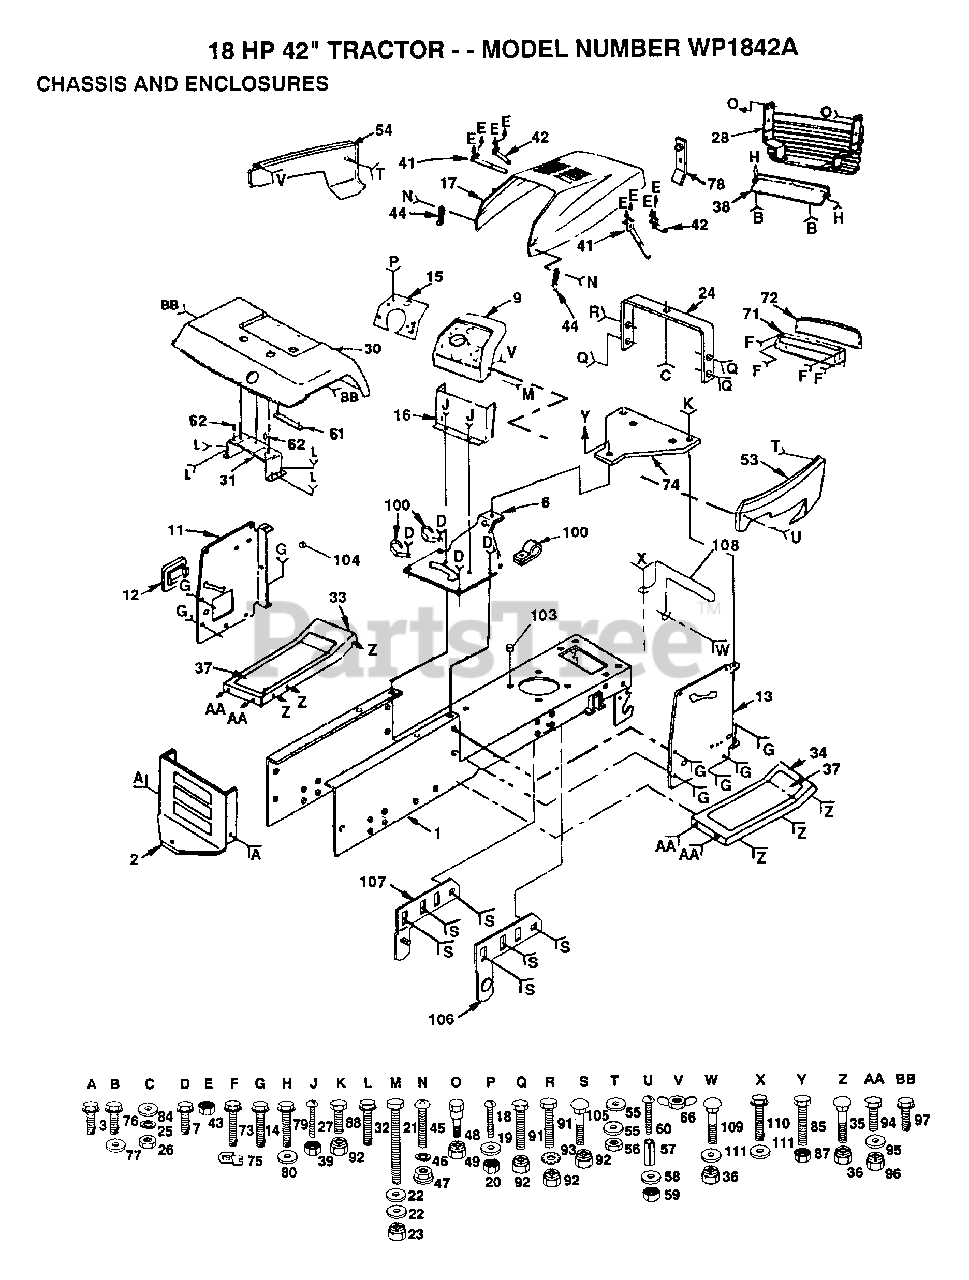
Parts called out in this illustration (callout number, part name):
3	SCREW
6	SADDLE SILKSCREEN 6D ENG YT LH
7	SCREW LT
11	DASH PANEL LH
14	SCREW
18	SCREW
19	WASHER
22	WASHER
24	SUPPORT ASS'Y
25	LOCKWASHER
27	SCREW
30	FENDER
32	SCREW
35	BOLT
37	FOOTREST PAD
43	NUT
44	HOOD LATCH T
45	SCREW
46	WASHER LOCK #10
47	WELDNUT
53	"PANEL,SIDE RH"
54	"PANEL,SIDE LH"
55	WASHER PM
57	SPACER LT
58	WASHER
60	SCREW
62	NUT-PUSH YT
72	LENS LT
75	"""J"" FASTENER LT"
76	SCREW
77	WASHER
79	SCREW HEX CRT
80	WASHER
84	WASHER PM
85	BOLT
93	LOCKWASHER
95	WASHER
97	SCREW LT
100	CLIP T
103	SNAP BUSHING T
105	BOLT
106	PIVOT BRKT RH
107	PIVOT BRKT LH
108	MUFFLER GUARD
109	BOLT D
110	SCREW GTV
111	WASHER
